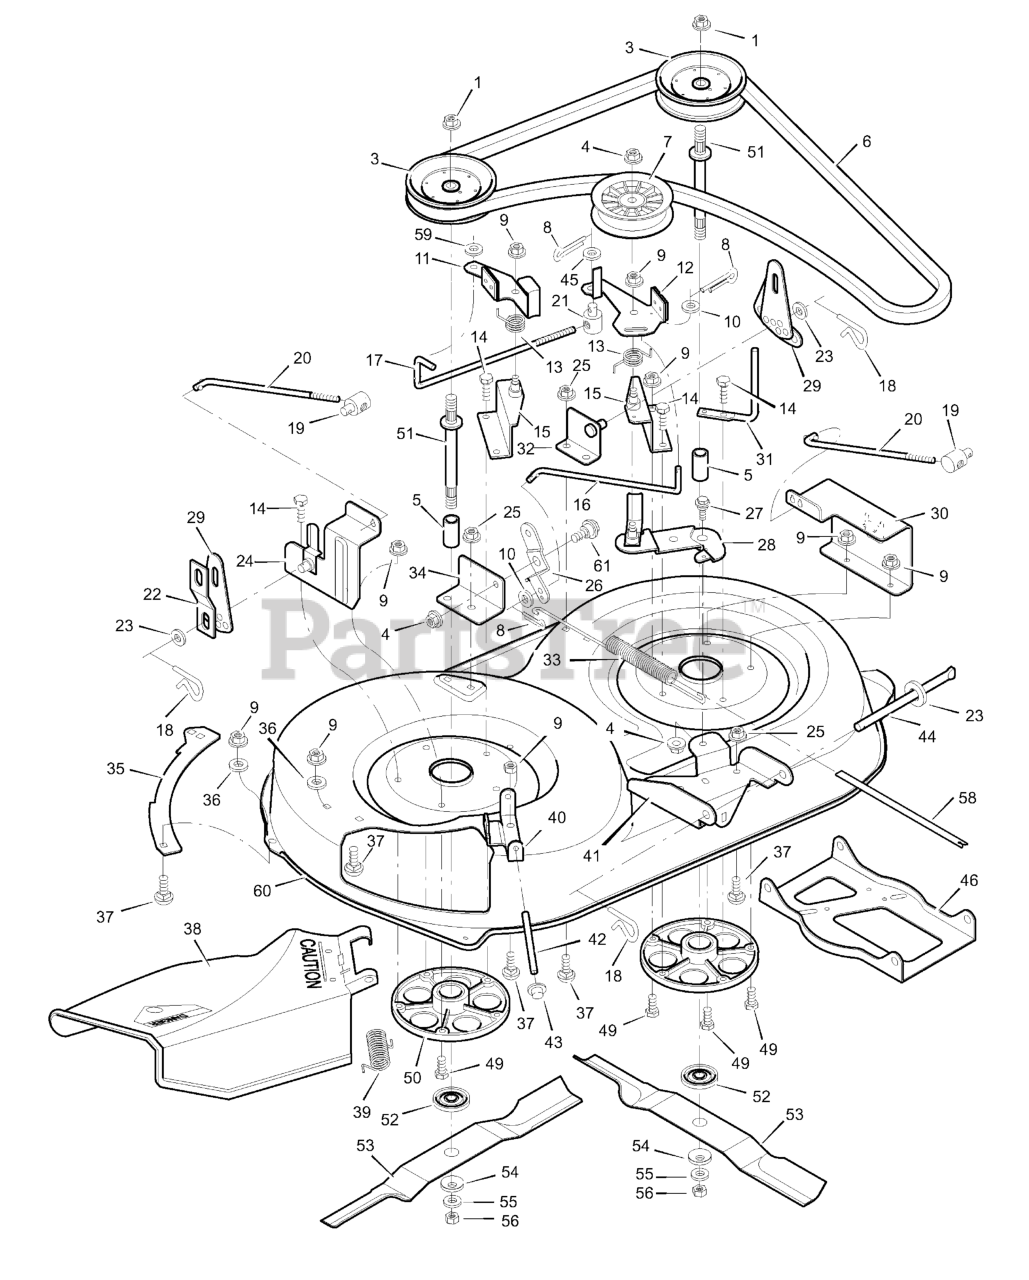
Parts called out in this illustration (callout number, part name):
1	Nut, Hex
1-61	Complete Mower Housing Assembly
3	Pulley, Jackshaft
4	Locknut, Flange
5	Spacer
6	Belt, Blade Drive
7	Pulley, Idler
8	Pin, Cotter
9	Locknut, Flange
11	Brake Assembly, Right
12	Brake Assembly, Left
13	Spring, Torsion
14	Bolt, Hex
15	Bracket Assembly, Brake
16	Rod, Brake
17	Rod, Cross Link
18	Pin, Hair
19	Nut, Adjustable
20	Rod, Adjuster
21	Nut, Adjustable
22	Link, Suspension
24	Bracket Assembly, Right Lifter
25	Nut, Flange
26	Bracket, Pivot
27	Bolt, Shoulder
28	Arm Assembly, Idler
29	Plate, Adjuster
30	Cover, Pulley
31	Guide, Belt
32	Bracket Assembly, Left Lifter
33	Spring, Extension
34	Bracket, Pivot
35	Plate
37	Bolt, Carriage
38	Deflector Assembly, Chute
39	Spring, Torsion
40	Bracket, Hinge
41	Bracket, Front Hanger
42	ROD, Deflector
43	Cap, Push On
44	Rod, Hanger
46	Hanger, Front
49	CAPSCREW, Hex Head, 5/16-18 x 1
50	Housing, Jackshaft
51	Jackshaft
52	Adapter, Blade
53	Blade, 38"
53	Blade, 40"
54	Washer, Belleville
56	Nut, Hex
58	Indicator, Plastic
60	Housing, Blade (38")
60	Housing, Blade (40")
61	Bolt, Shoulder
